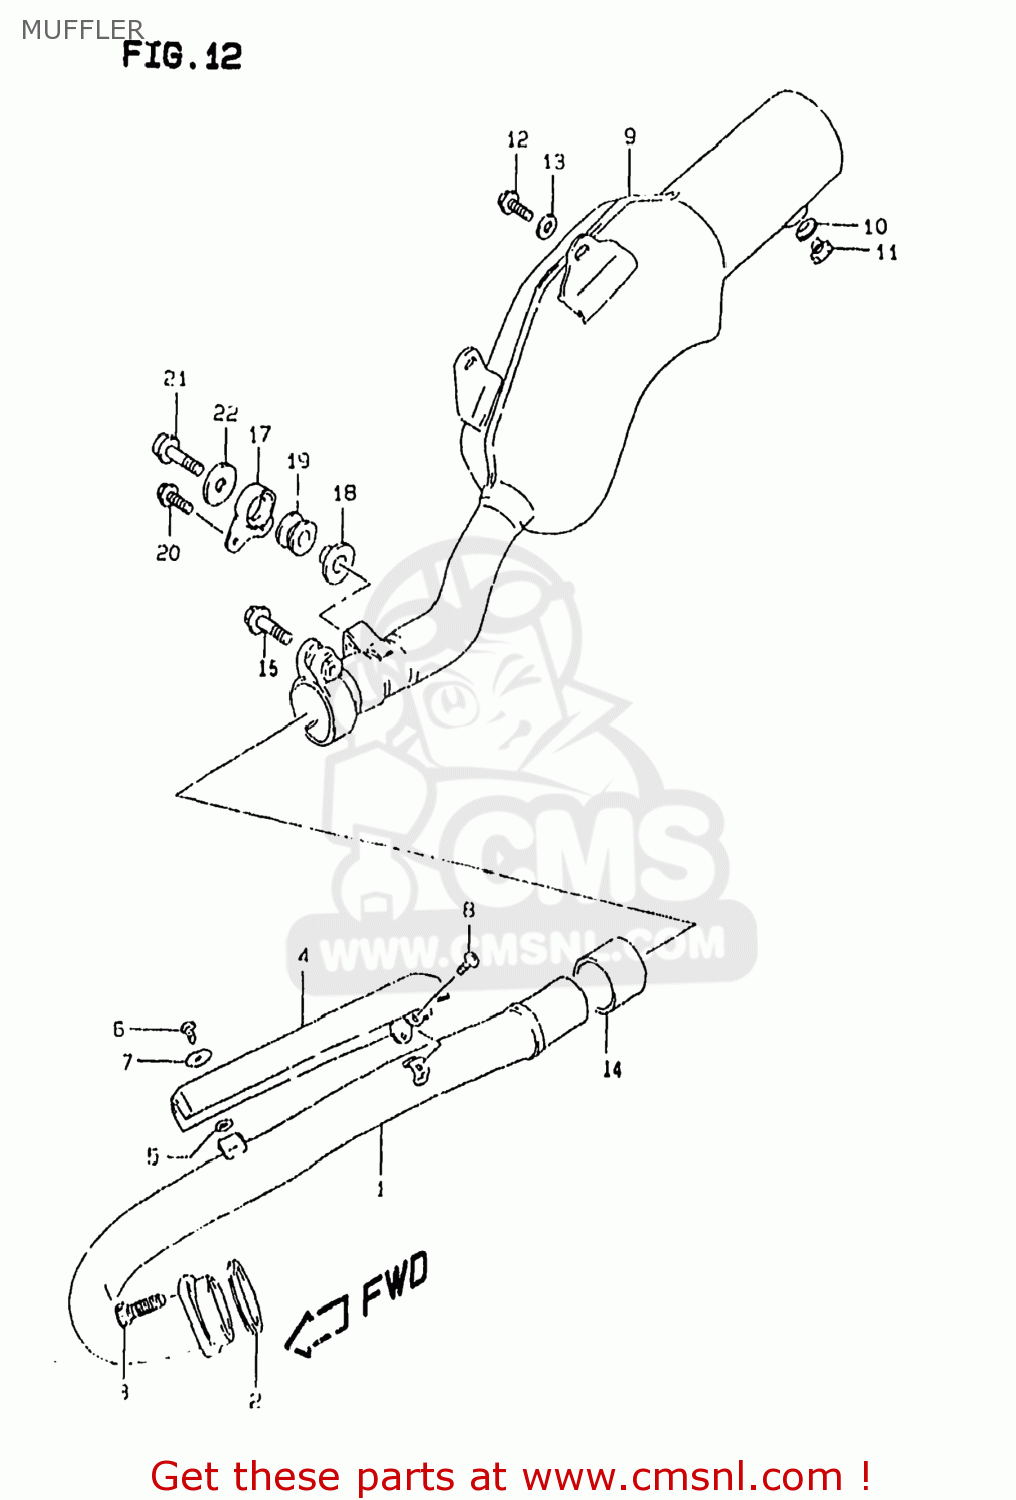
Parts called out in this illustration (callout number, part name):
1	PIPE,EXHAUST
2	GASKET,EXHAUST PIPE (NAS)
3	BOLT
4	COVER,EXHAUST PIPE
5	GASKET(5.8X13X1.4) (NAS)
6	SCREW(6X10)
7	WASHER(6.5X18X1)
8	SCREW
9	BODY,MUFFLER
10	GASKET(12.1X16.2X3.7) (NAS)
11	PLUG(12X9)
12	BOLT(8X20)
13	WASHER (8.5X19X2.3)
14	CONNECTOR,MUFFLER
15	BOLT
16	DAMPER,MUFFLER SUPPORT JOINT
17	SPACER(8.6X12X17.5)
18	CUSHION
19	BOLT 6X12
20	BOLT(8X30)
21	WASHER(8.5X28X1.6)
